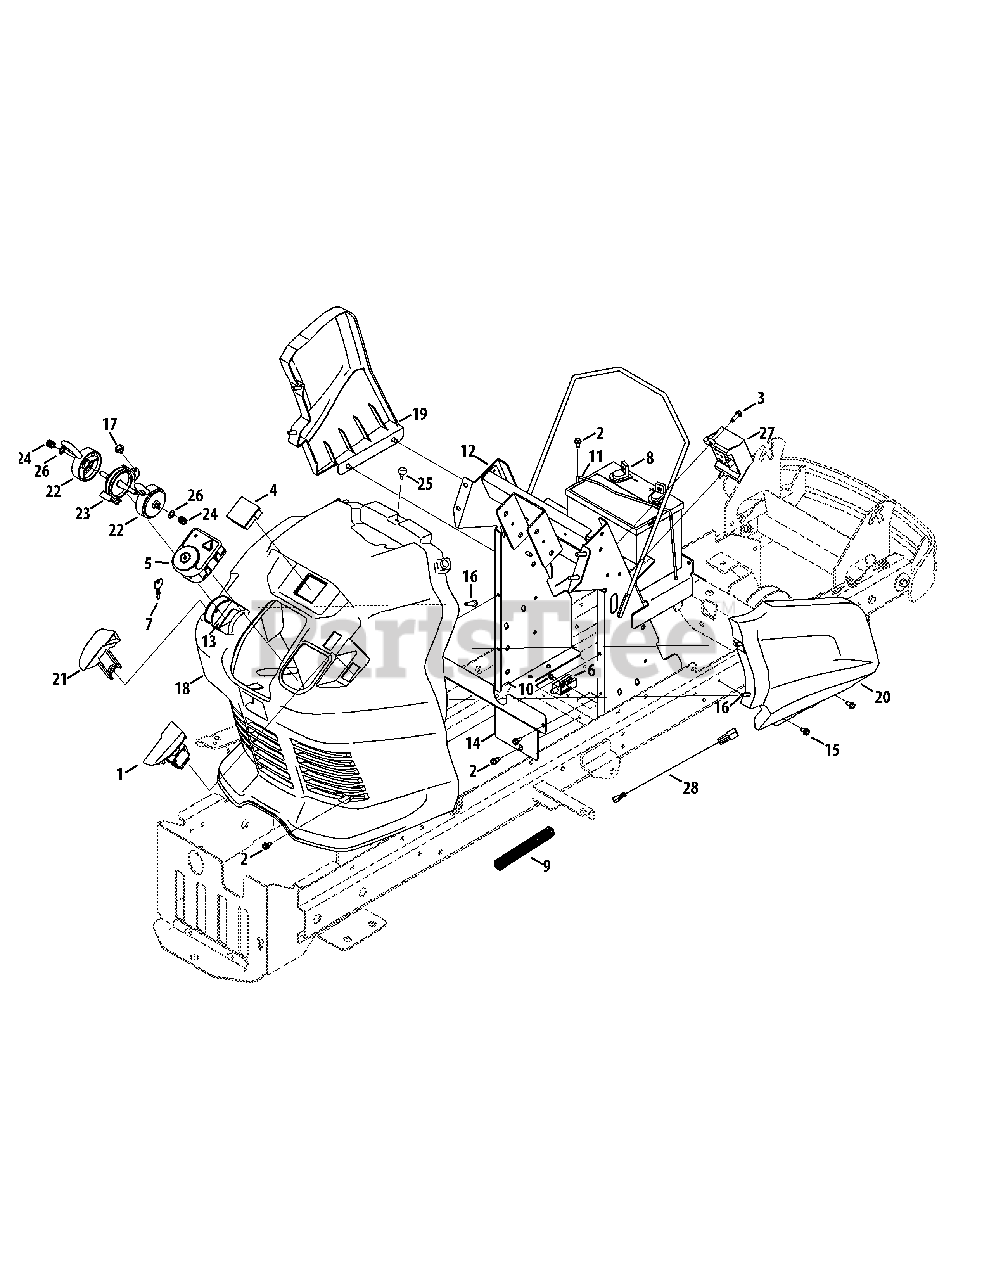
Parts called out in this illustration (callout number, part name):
1	PTO Lever
2	Hex Washer Screw, 1/4-20 x .500
3	Hex Washer Screw, 1/4-20 x .750
4	Hour/Service Minder Indicator Meter
5	Key Switch
6	Interlock Switch
7	Universal Key
10	Shoulder Screw, #10-32 x .500
11	Battery Strap
12	Steering/Battery/Dash Frame Assy.
13	Throttle Control Mount Bracket
14	Engine Air Upper Shield
15	Hex Washer Screw, 5/16-18 x .750
16	Hex Washer Screw, 5/16-14 x 1.00
17	Hex Washer Screw, #10-16 x .375
18	Dash
19	LH Dash Panel
20	RH Dash Panel
21	Cruise/Brake Lever
22	Choke/Throttle Control
23	Choke/Throttle Index Disc
24	Compression Spring, .50 x .50
25	Bumper, .62 x .3
26	Flat Washer, .344 x .620 x .033
27	Wire Harness
28	Reverse Jumper Harness
